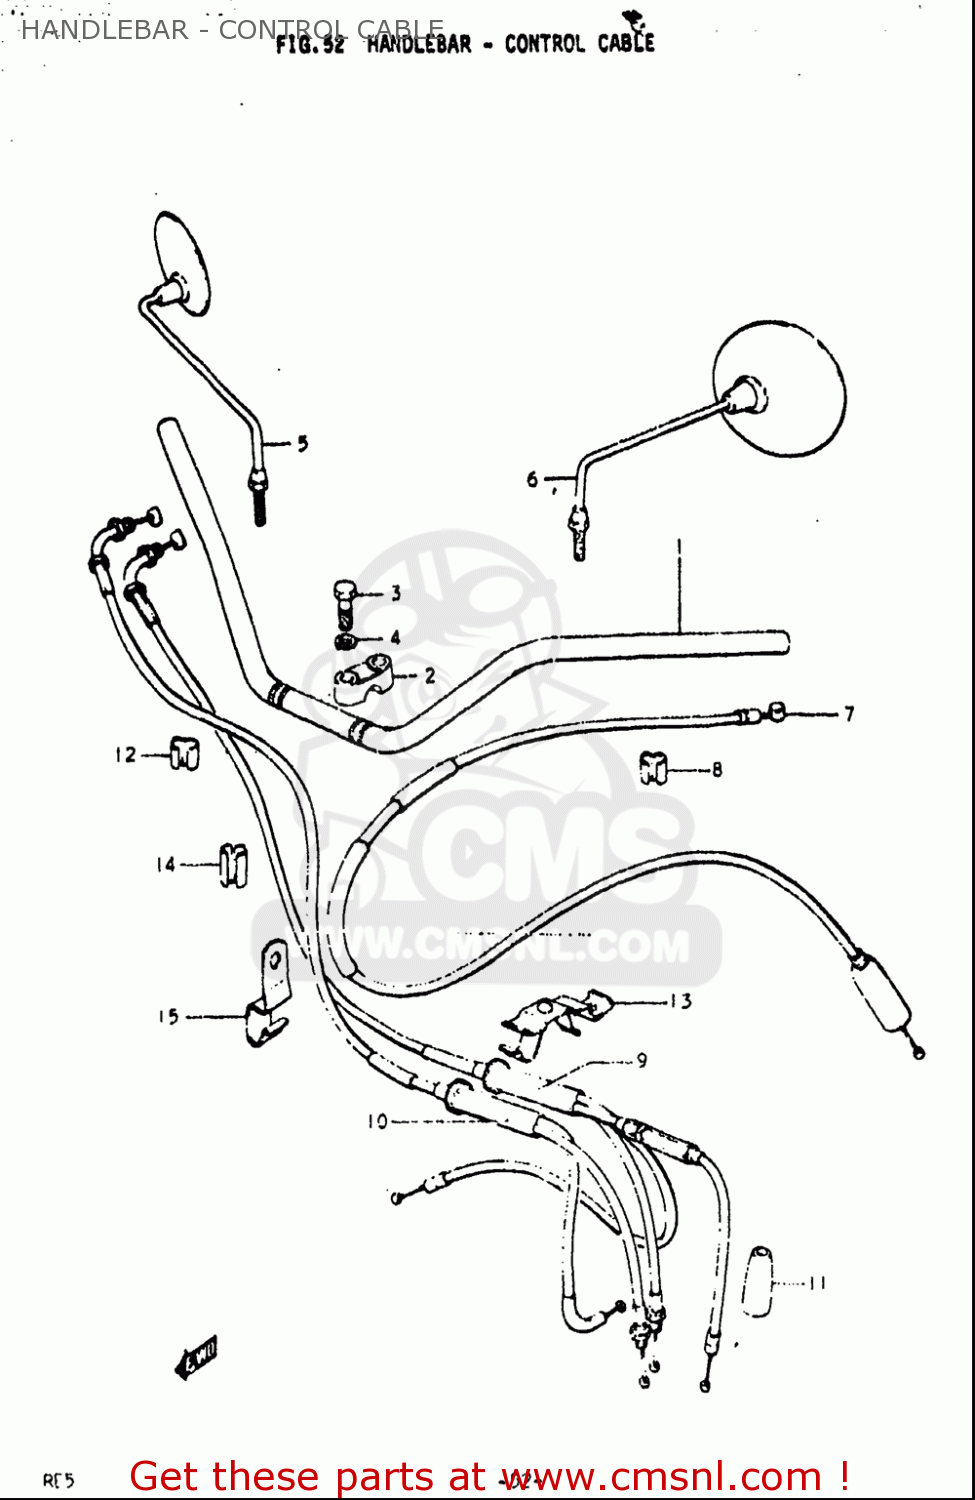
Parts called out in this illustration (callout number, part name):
2	HOLDER,HANDLE UPR
3	BOLT
4	WASHER,LOCK
5	MIRROR ASSEMBLY,RIGHT
6	MIRROR ASSEMBLY,LEFT
8	CLIP
11	SEAL,DUST(7X18X30)
12	CLIP
14	CLIP
15	GUIDE,CABLE
